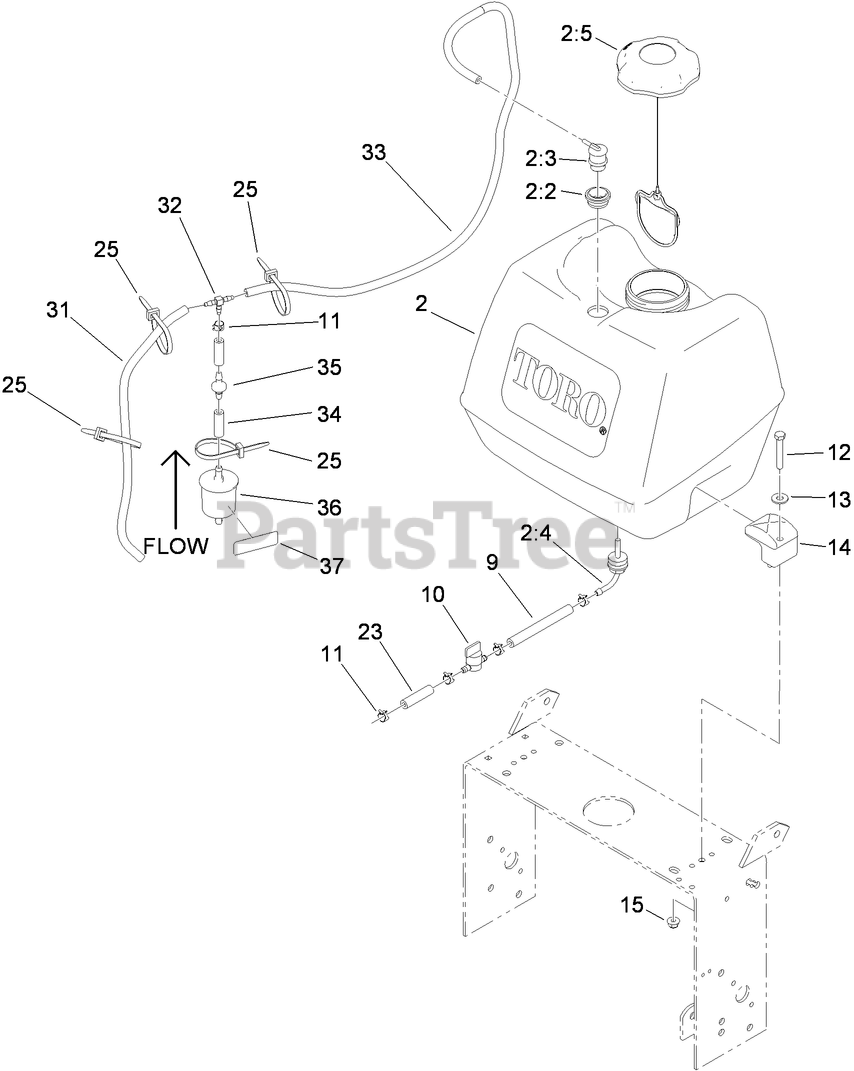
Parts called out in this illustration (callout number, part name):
2	FUEL TANK ASM
2:2	GROMMET-VALVE, ROLL-OVER
2:3	VALVE-ROLLOVER
2:4	FITTING-FUEL, BULKHEAD
2:5	CAP-FUEL, RATCHETING
9	HOSE-FUEL
10	VALVE-FUEL
11	CLAMP-HOSE
12	SCREW-HH
13	WASHER-FLAT
15	NUT-HF, NI
23	HOSE-FUEL
25	TIE-CABLE
31	HOSE-FUEL
32	FITTING-TEE
33	HOSE-EMISSIONS
34	HOSE-FUEL
35	VALVE-CHECK, FUEL
36	FILTER-FUEL
37	DECAL-FILTER, EMISSIONS
